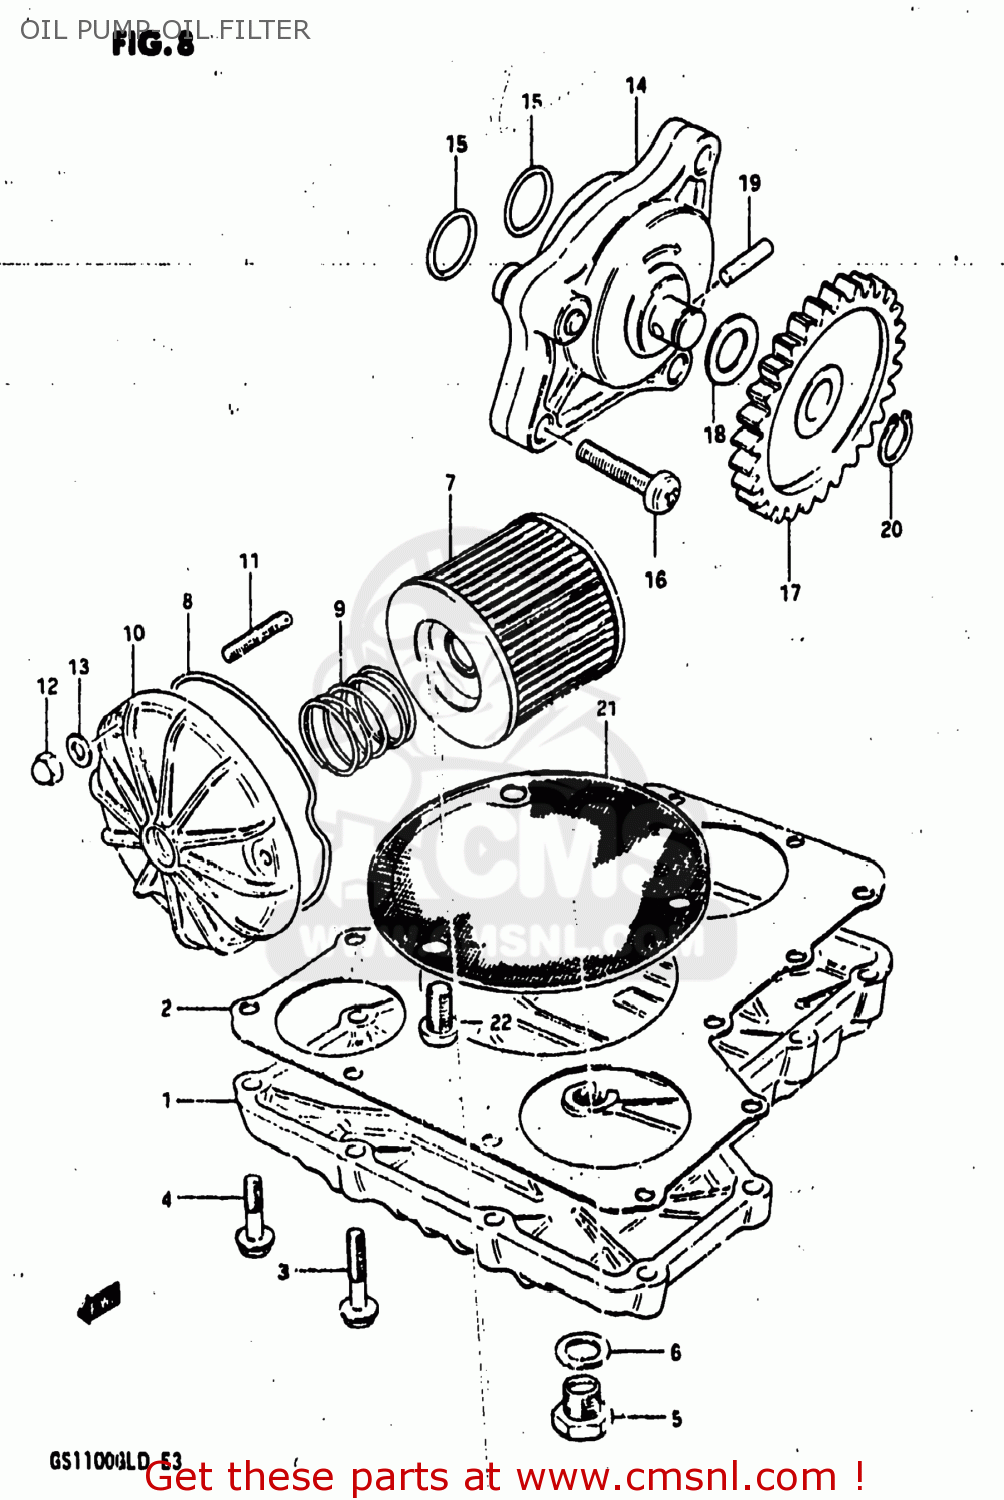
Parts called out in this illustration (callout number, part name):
1	PAN,OIL
2	GASKET,OIL PAN (MCA)
3	BOLT
4	BOLT
5	PLUG
6	GASKET(14X19.2X2) (NAS)
7	FILTER ASSY,ENGINE OIL
8	O RING,OIL FILTER CHAMBER CAP
9	SPRING
10	CAP,OIL FILTER
11	STUD 6X20
12	NUT
13	WASHER
14	PUMP ASSEMBLY,ENGINE OIL
15	O RING(D:1.9,ID:13)
16	SCREW
17	GEAR,ENG OIL PUMP DRIVEN(NT:33
18	SHIM
19	PIN(4X15.8)
20	CIRCLIP
21	STRAINER,ENGINE OIL
22	SCREW 6X12
